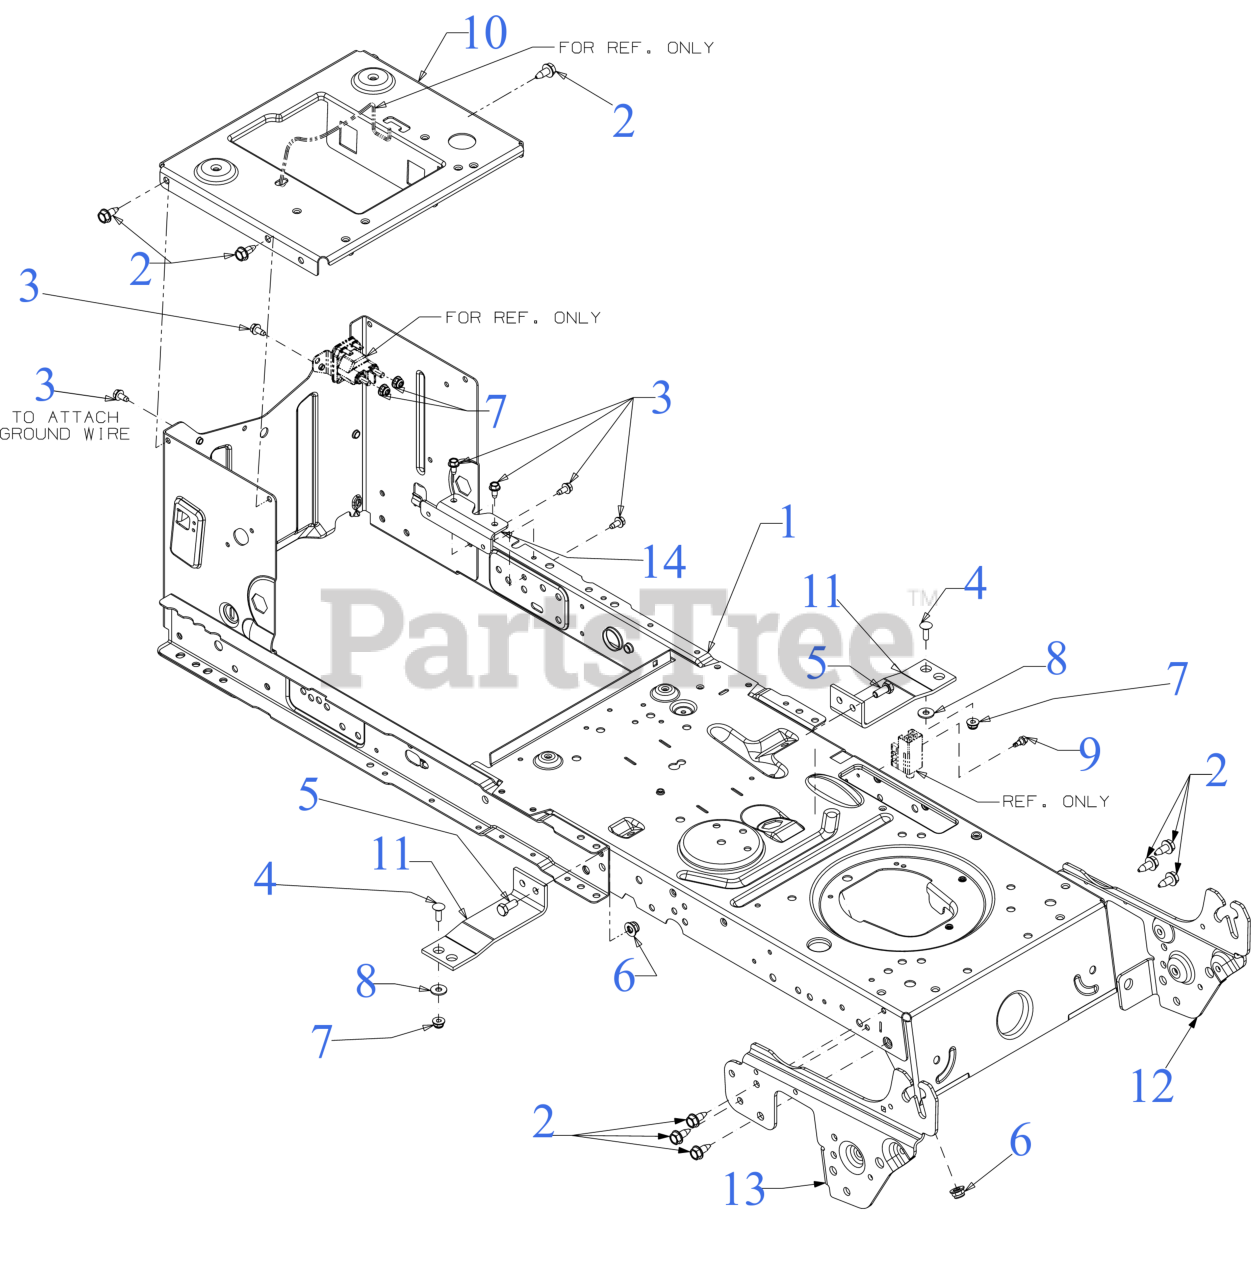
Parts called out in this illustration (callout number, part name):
1	FRAME ASSEMBLY
2	SCREW 5/16-18 x .750
3	SCREW 1/4-20 X.500
4	SCREW 1/4-20 x .75 GR5
5	SCREW 5/16-18 x .75 GR5
6	FLANGE LOCK NUT 5/16-18
7	FLANGE LOCK NUT
8	FLAT WASHER .28 ID x .74 OD x .063
9	SHOULDER SCREW
